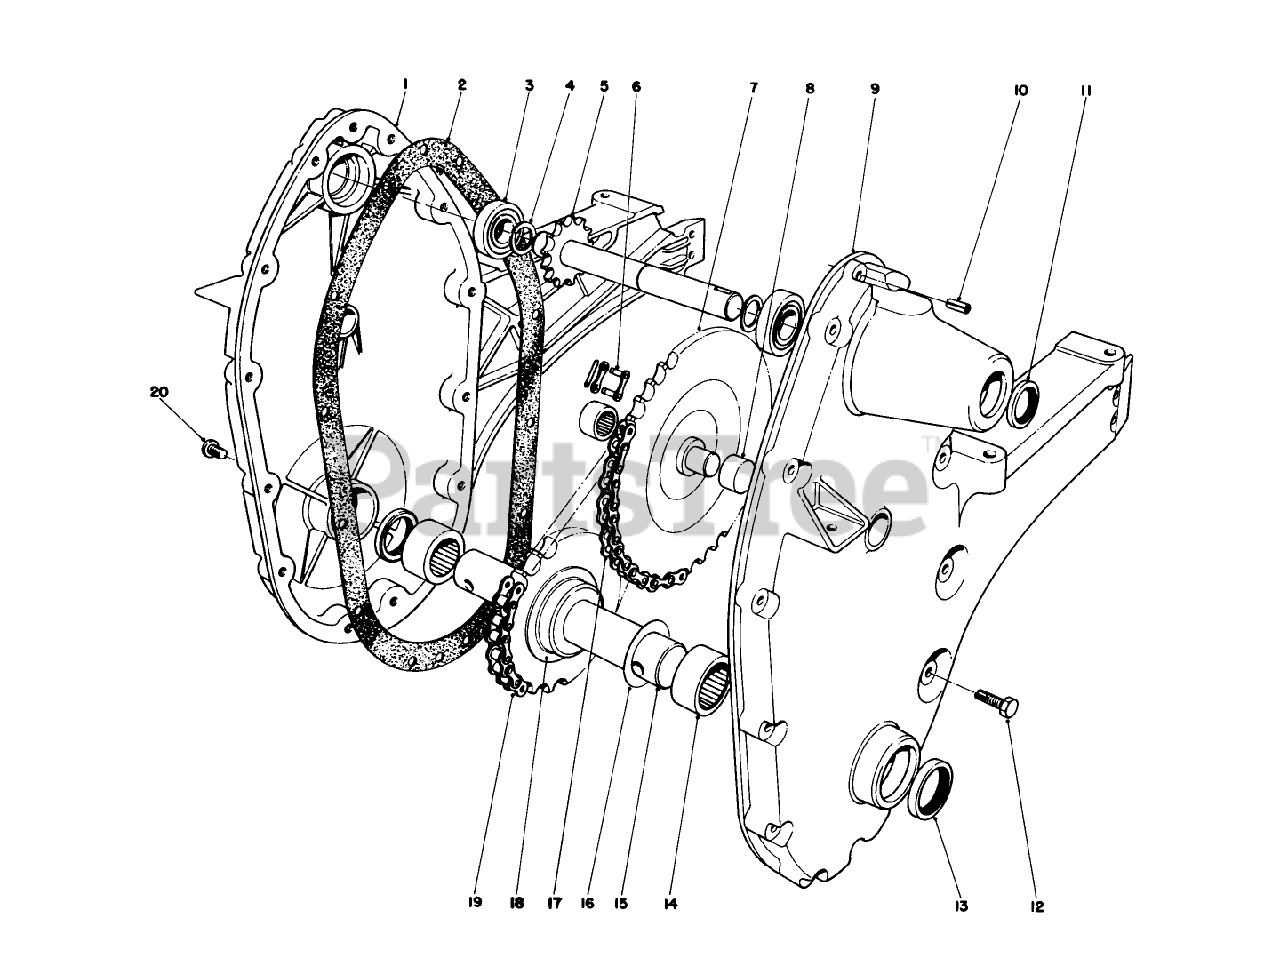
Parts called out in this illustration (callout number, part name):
3	BALL BRG
6	LINK-CONNECTING, NO. 35
7	Sprocket Cluster
9	Chain Case L.H.
10	PIN-ROLL
11	SEAL-OIL
12	SCREW-HWH, TAP
13	SEAL-OIL
14	NEEDLE BRG
15	Tine Shaft
16	Washer
18	Cup Spacer
